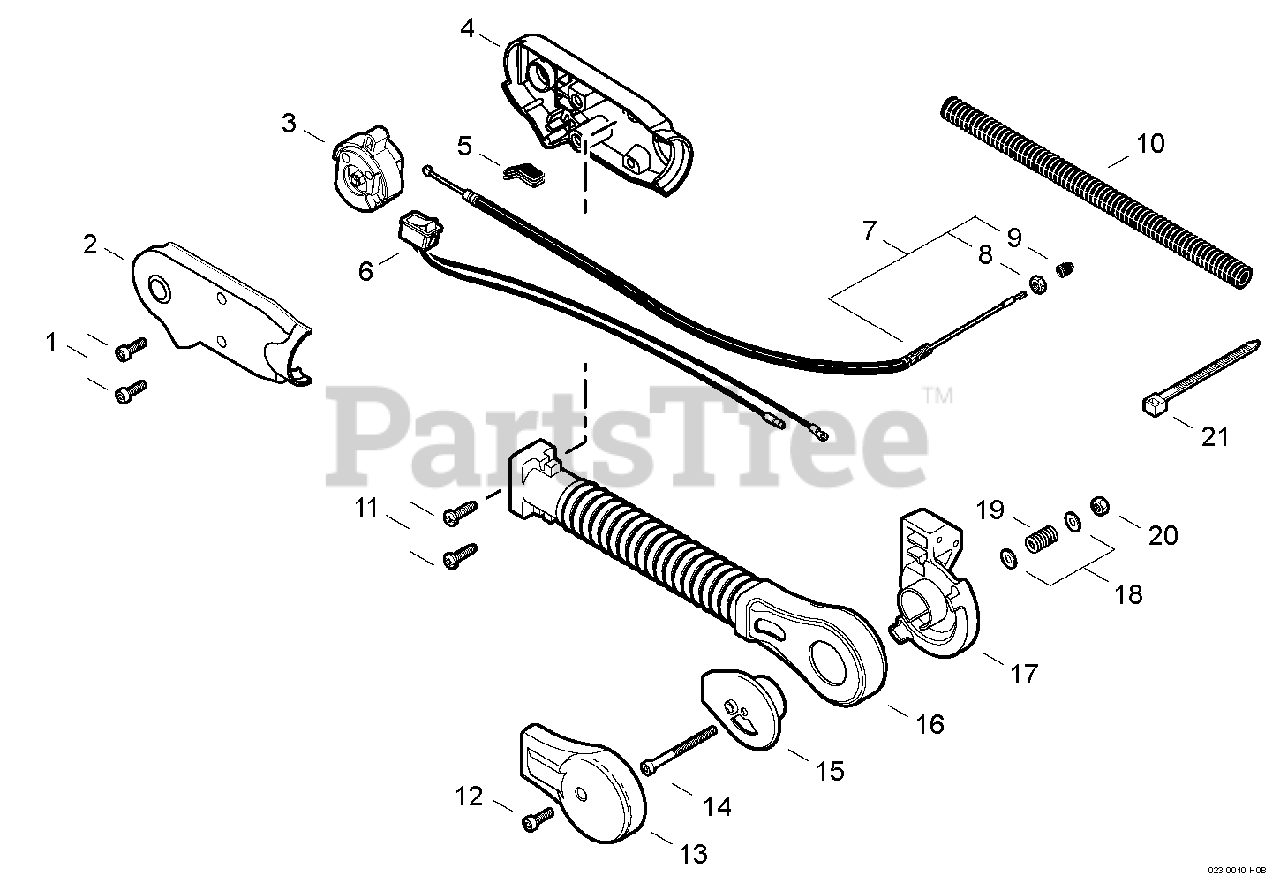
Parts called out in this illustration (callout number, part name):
1	SCREW - 5X14
2	HANDLE, CONTROL - LEFT
3	THROTTLE CONTROL ASSY
4	HANDLE, CONTROL - RIGHT
6	SWITCH, IGNITION
7	THROTTLE CABLE ASSY
8	LOCKNUT - 6
9	CAP, DUST
10	TUBE, PROTECTIVE - CORRUGATED
11	SCREW - 5X20
12	SCREW - 5X14
13	COVER, BRACKET
14	SCREW - 5X80
15	BRACKET, OUTER ARM
16	ARM, THROTTLE CONTROL
17	BRACKET, ARM - INNER
20	LOCKNUT - 5
21	TIE, CABLE - SMALL
